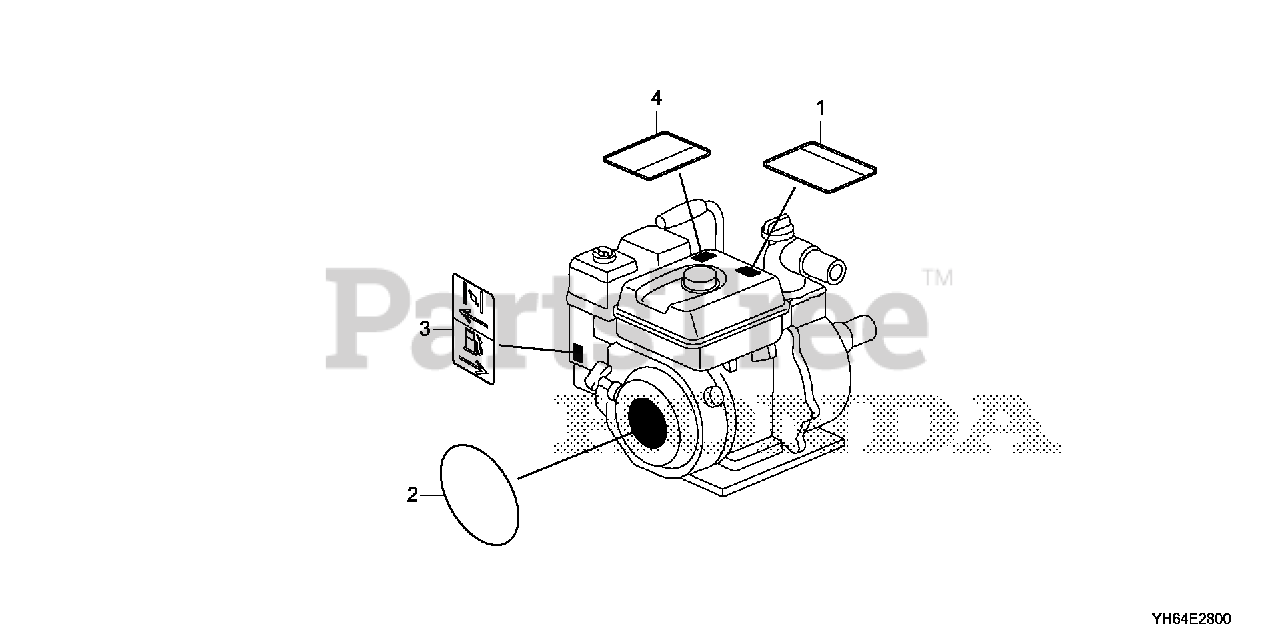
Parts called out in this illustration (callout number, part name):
1	LABEL, OPERATOR WARNING (ENGLISH)
2	EMBLEM (GX120)
3	MARK, CHOKE
4	MARK, EX. CAUTION (ENGLISH)
